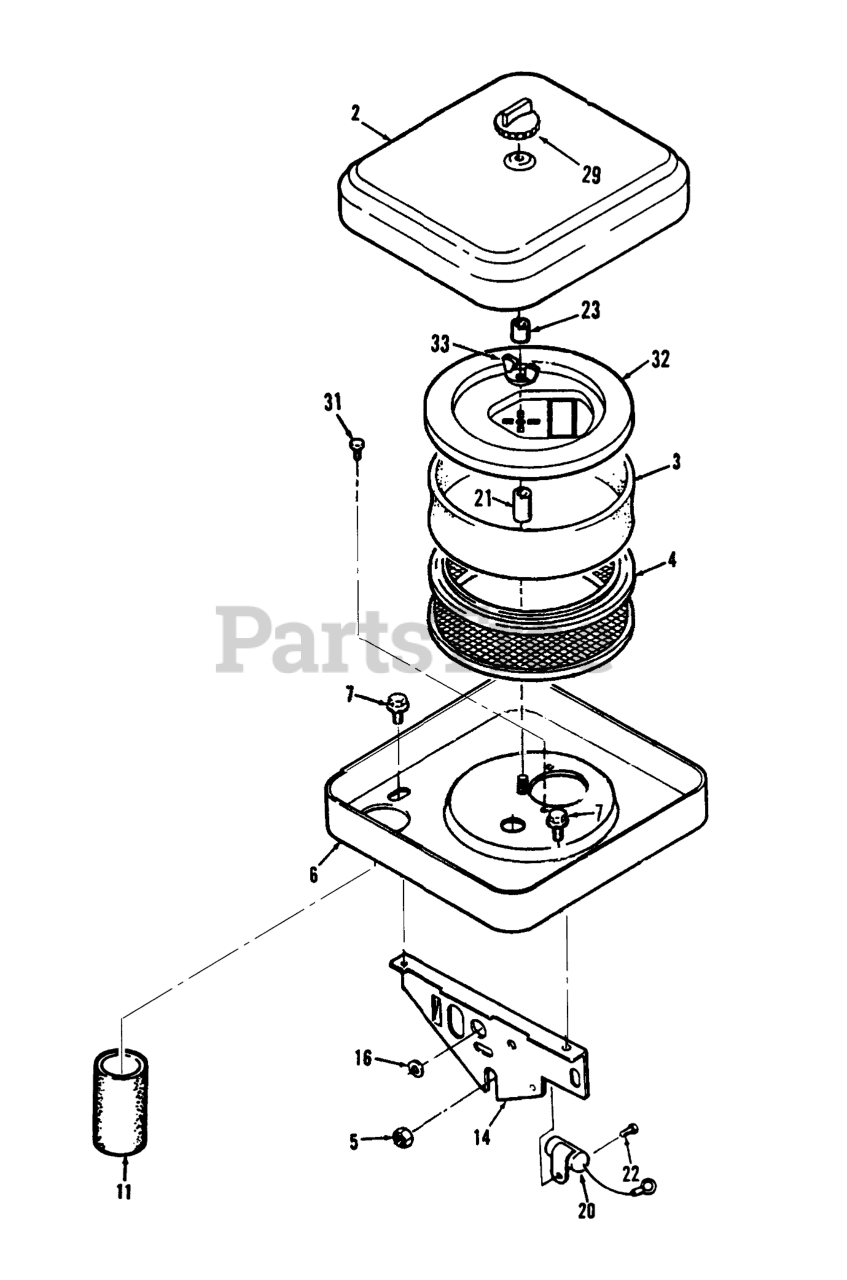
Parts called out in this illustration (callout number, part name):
2	CHROME-AIR CLEANER
3	AIR CLEANER ELEMENT
4	AIR-CLEANER ELEMENT
5	Washer
6	AIR-CLEANER HOUSING
7	SCREW-TAPPING
11	AIR INTAKE TUBE
14	SUPPORT-AIR CLEANER
16	Grommet
20	Condenser
21	SPACER-1" LG
22	SCREW #10-32 X 5/8
23	SPACER-RUBBER
31	MACHINE SCREW
32	Cover-Element
33	1/4-20 WING NUT
